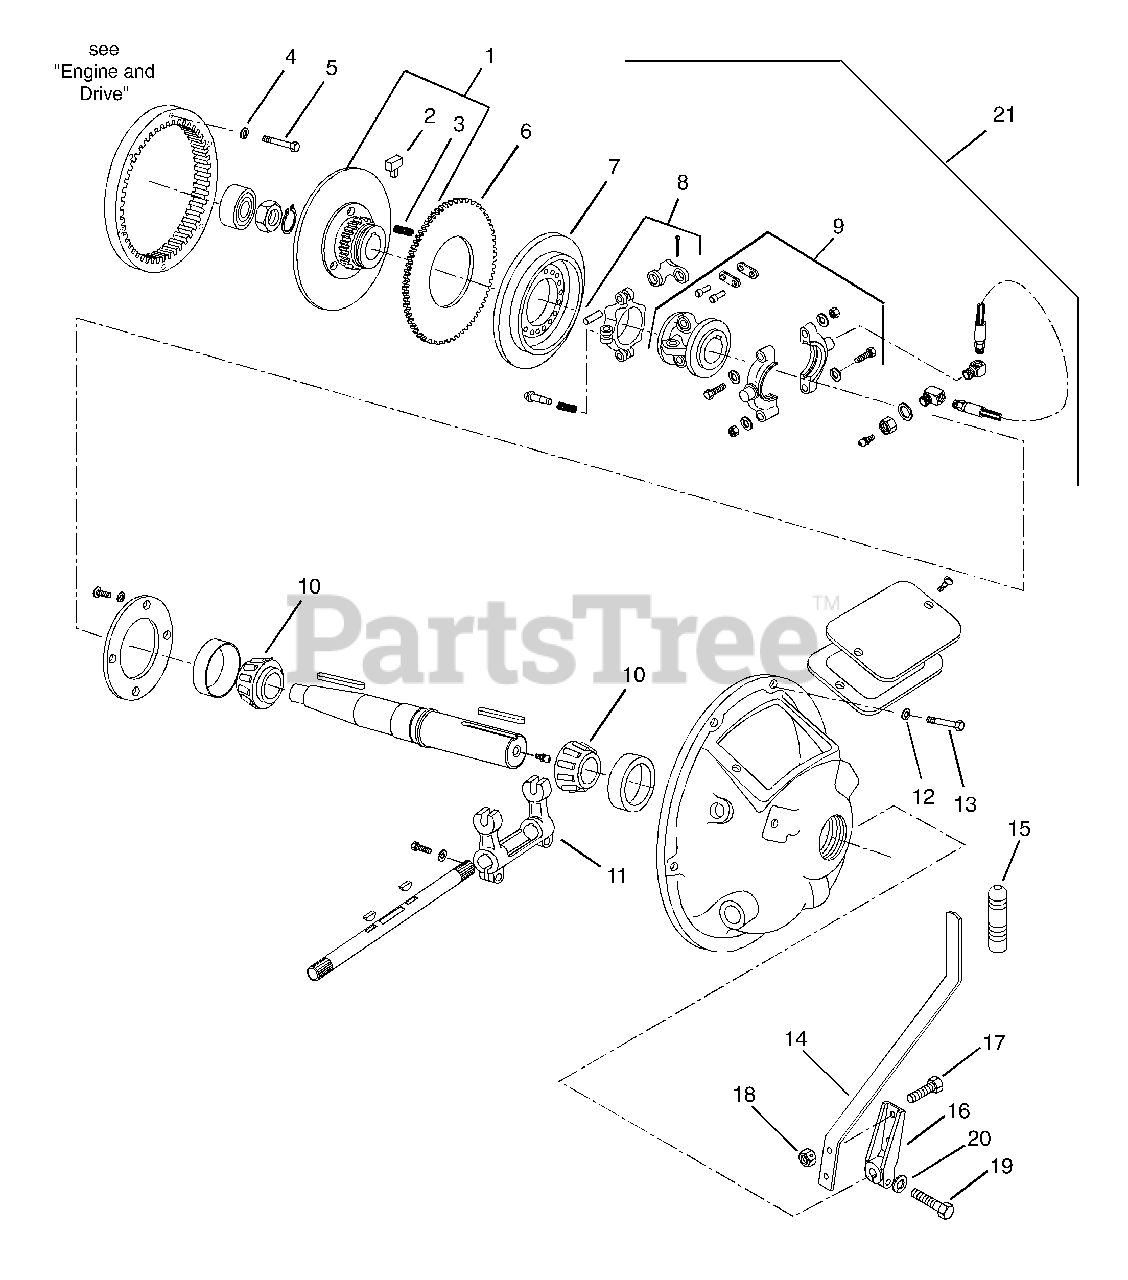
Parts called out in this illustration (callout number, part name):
1	Plate-Hub and Back Assembly
2	Pin Plate - Front and Back
3	Spring-Release
4	Washer-Locking .31 x .078
5	Bolt-Hex M8 x 1.25 x 35 mm Grade 10.9
6	Plate-Driving Split
7	Yoke-Adjusting Assembly
8	Yoke-Adjusting Assembly
9	Sleeve-Sliding Assembly
10	Ball Bearing, Shaft Clutch
11	Yoke-Throwout
12	Washer-Locking .44 x .109
13	Bolt-Hex M10 x 1.50 x 25 mm
14	Lever-Clutch
15	Grip
16	Clutch-Lever, Socket Diesel
17	Bolt-Hex .38-16 x 1.00 Grade 5
18	Nut-Locking-Center .38-16
19	Bolt-Hex .38-16 x 1.50 Grade 5
20	Washer-Locking .38 x .094
21	Clutch Assembly
